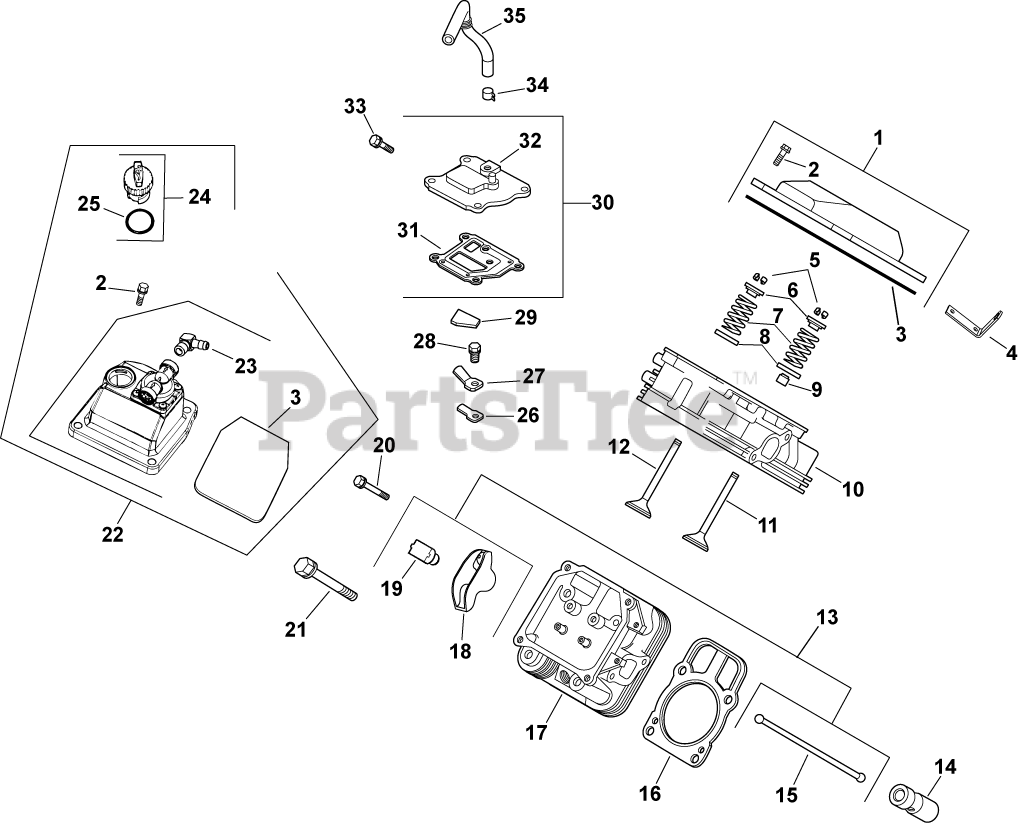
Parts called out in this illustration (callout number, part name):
1	KIT, VALVE COVER-PLAIN
2	SCREW, FLG M6X1.0X30
3	O-RING (YELLOW) -USE 24 153 30-S
4	STRAP, LIFTING-USE 25 445 03-S
5	KIT, RETAINER
6	RETAINER, VALVE SPRING - USE 25 173 28-S
7	SPRING, VALVE
8	RETAINER, SPRING
9	SEAL, VALVE STEM - (#2503214S)
10	HEAD, ASSEM CYLINDER #1 -USE 24 318 107-
11	VALVE, INTAKE (STD)
12	VALVE, EXHAUST (STD) - USE 32 016 01-S
13	KIT, VALVE TRAIN
14	LIFTER, HYDRAULIC VALVE-USE 25 351 10-S
15	ROD, PUSH
16	KIT, GSKT CYL HD (C22-23 674CC)
17	HEAD, ASSEM CYLINDER #2 -USE 24 318 115-
18	ARM, ROCKER
19	PIVOT, ROCKER ARM
20	SCREW, FLG M6X1.0X34
21	SCREW - USE 62 086 08-S
22	KIT, VALVE COVER-FUEL PUMP
23	KIT, 90 DEG. FITTING
24	CAP ASSY, OIL FILL (YELLOW)
25	O-RING-USE 24 153 32-S
26	REED, BREATHER
27	RETAINER, REED
28	SCREW, FLG THD FRM M5X.8X10
29	FILTER, BREATHER-USE 24 050 11-S
30	KIT, BREATHER ASSEMBLY
31	GASKET, BREATHER-USE 24 041 67-S
32	COVER, BREATHER -USE 24 033 01-S
33	SCREW,FLG THD FRM M6X1.0X20-(#25086396S)
34	CLAMP, HOSE (KM)-USE 25 237 31-S
35	HOSE, BREATHER-USE 24 326 89-S
2401602-S	VALVE, EXHAUST (.25)
2401702-S	VALVE, INTAKE (.25)
24755147-S	KIT, CYLINDER HEAD HARDWARE
